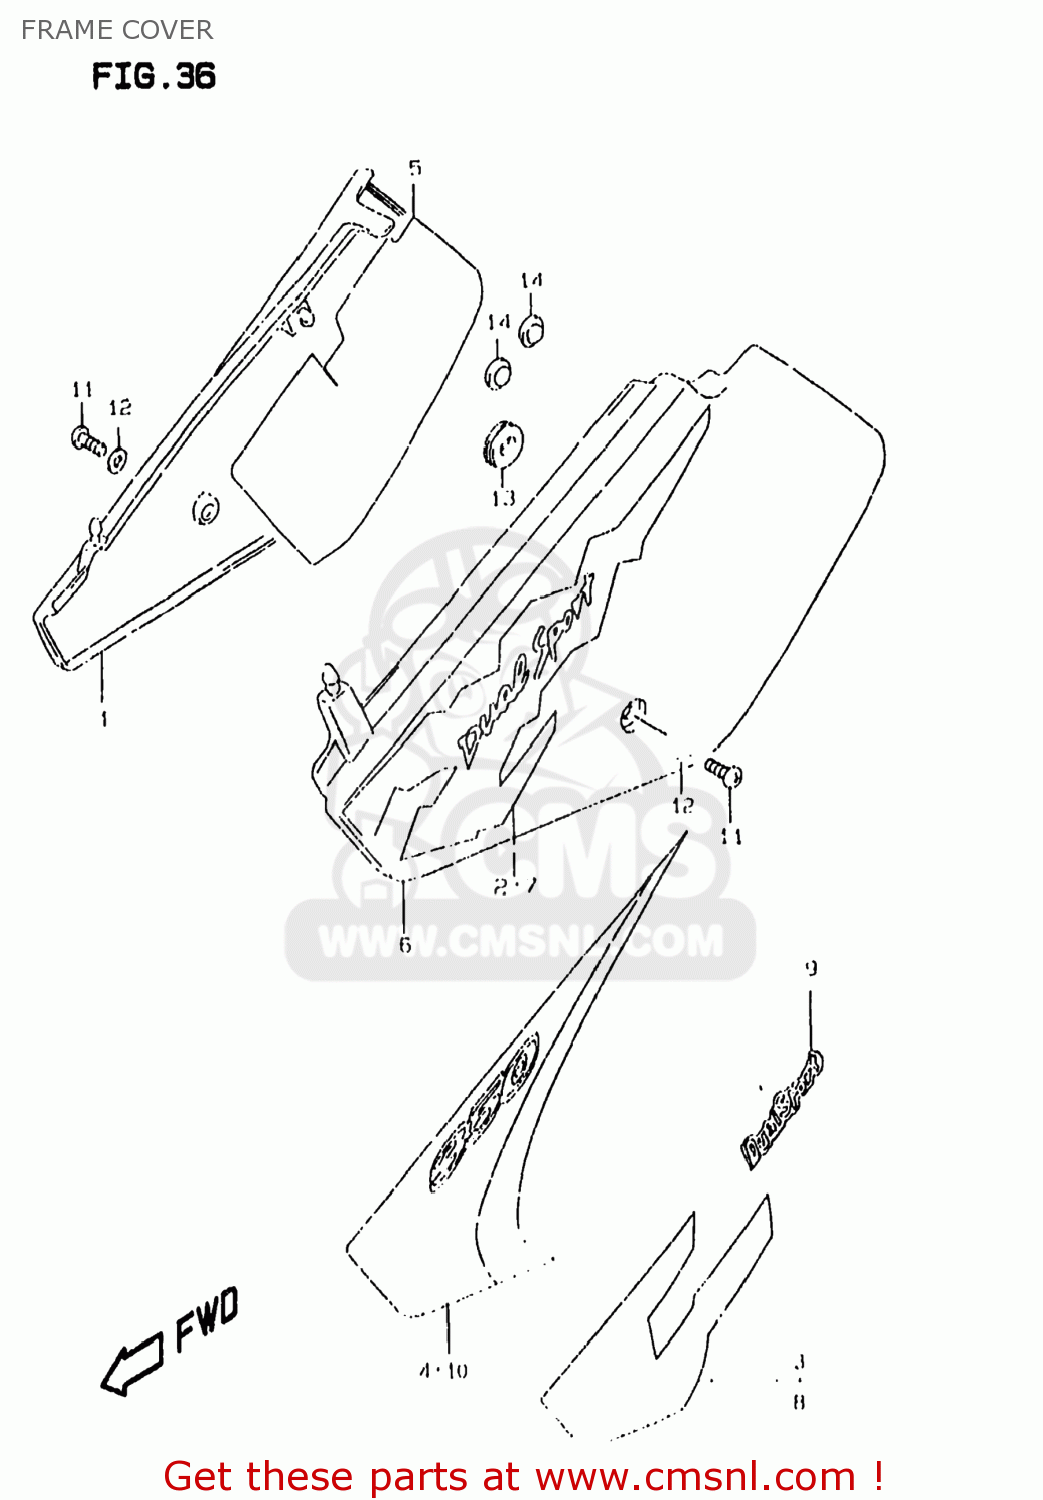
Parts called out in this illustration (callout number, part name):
1	COVER,FRAME,R(WHITE)
2	TAPE,FRAME COVER,R
3	TAPE,FRAME COVER,R
4	TAPE,FRAME COVER,R
5	SHIELD,FRAME COVER,R
6	COVER,FRAME,L(WHITE)
7	TAPE,FRAME COVER,LEFT
8	TAPE,FRAME COVER,L
9	EMBLEM,FRAME COVER
10	TAPE,FRAME COVER,LEFT
11	SCREW
12	WASHER
13	CUSHION
14	CUSHION
